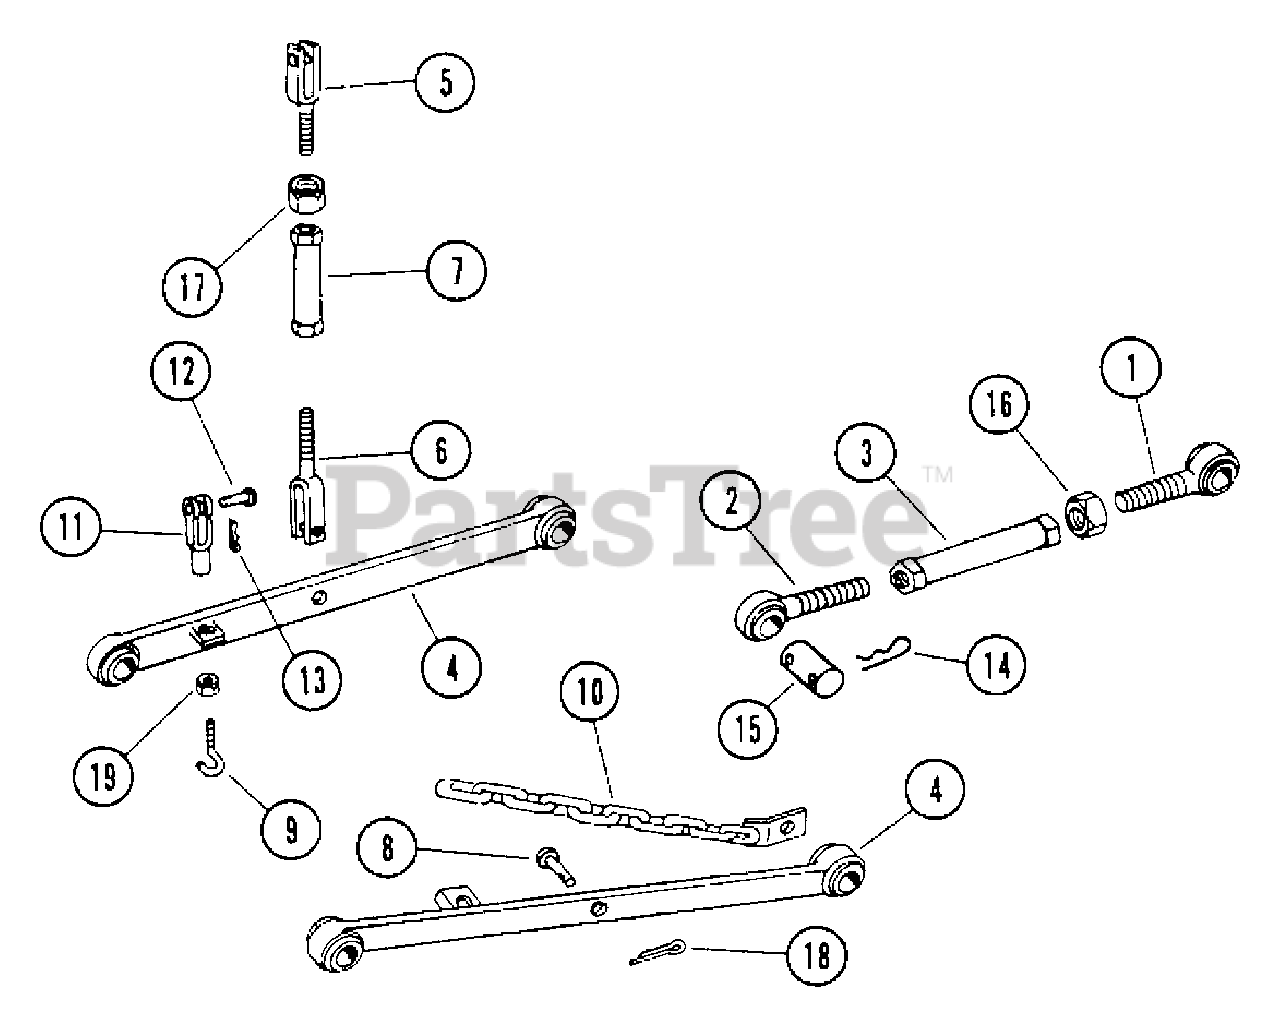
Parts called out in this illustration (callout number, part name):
1	Ball Joint Left Hand
2	Ball Joint Right Hand
3	Turnbuckle
4	Lower Arm
5	Clevis Left Hand
6	Clevis Right Hand
7	Turnbuckle
8	Rivet .50 x 1.25
9	Eye Bolt
10	Sway Chain
11	Yoke .312-24 x 2.25
12	Pin-Clevis .312 x .822 Hardened
13	Hairpin, #7 Clip .094 x 2.31
14	Pin-Hair-Internal .15 x 2.937
16	Nut-Jam .75-10
17	Nut-Jam .625-11
18	Pin-Cotter .12 x 1.25
19	Nut-Hex .312-24
